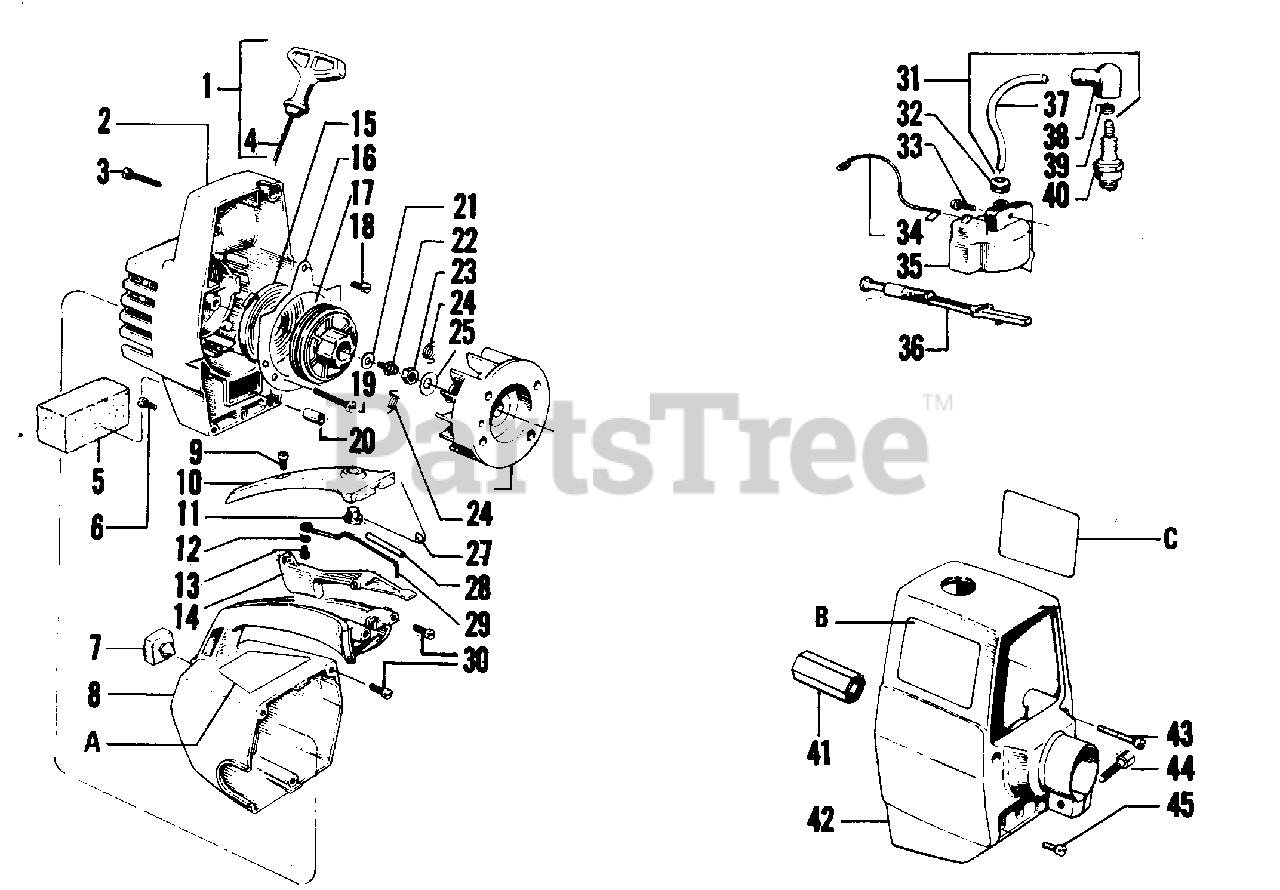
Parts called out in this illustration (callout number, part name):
2	Fan Hsg. Kit (Inc.16, 18, 19, 20, & 28)
4	Rope (3.5 ft.)
5	Air Filter
7	Bumper - Fuel Tank Housing
8	Handle & Fuel Tank Housing
9	Screw - #8 - 16 x 3/4" - Pan Hd. - Handle Cover
10	Handle Cover
11	Button - Kill Switch
12	Washer - Kill Switch
13	Screw - #8 - 16 x 3/8" - Pan Hd. - Kill Switch
14	Trigger - Throttle
16	Air Baffle
18	Screw - #10 x 1/4" - Fil. Hd. - Baffle
19	Screw - #10 - 24 x 1-3/16" - Fil. Hd.
20	Spacer - Air Baffle
21	Washer - Starter Pulley
22	Screw - #10 - 14 x 3/4" - Hex Washer Hd. Starter Pulley
23	Nut - Flywheel - #5/16 x 24"
24	Spring - Starter Dog
25	Washer #10 -14 - Flywheel
26	Flywheel Assembly (Inc.24)
27	Trigger Spring
28	Insulation - Switch Spring
29	Spring - Kill Switch
30	Screw #10 - 14 x 3/4" - Pan Hd. - Fan Housing to Handle & Fuel Tank
31	High Tension Lead Assembly (Inc.37,38,39)
32	Grommet - Plug Wire
33	Screw - #8 - 32 x 3/4" - Fil. Hd. - Ignition Module
34	Lead Wire - Switch
35	Kit - Ignition Module
36	Knob - Choke
37	High Tension Lead Wire
38	Boot - Spark Plug
39	Connector - Spark Plug Lead
40	Spark Plug
41	Coupling - Hex Drive
43	Screw - #10 - 24 x 1-1/3" - Fil. Hd. - Shroud (Top)
44	Bolt - Pinch Clamp
45	Screw - #10 - 24 x 5/8" - Fil Hd. - Shroud (Bottom)
A	Decal - Starting Instructions
B	Decal - Shroud (Right)
C	Decal - Shroud (Left)
